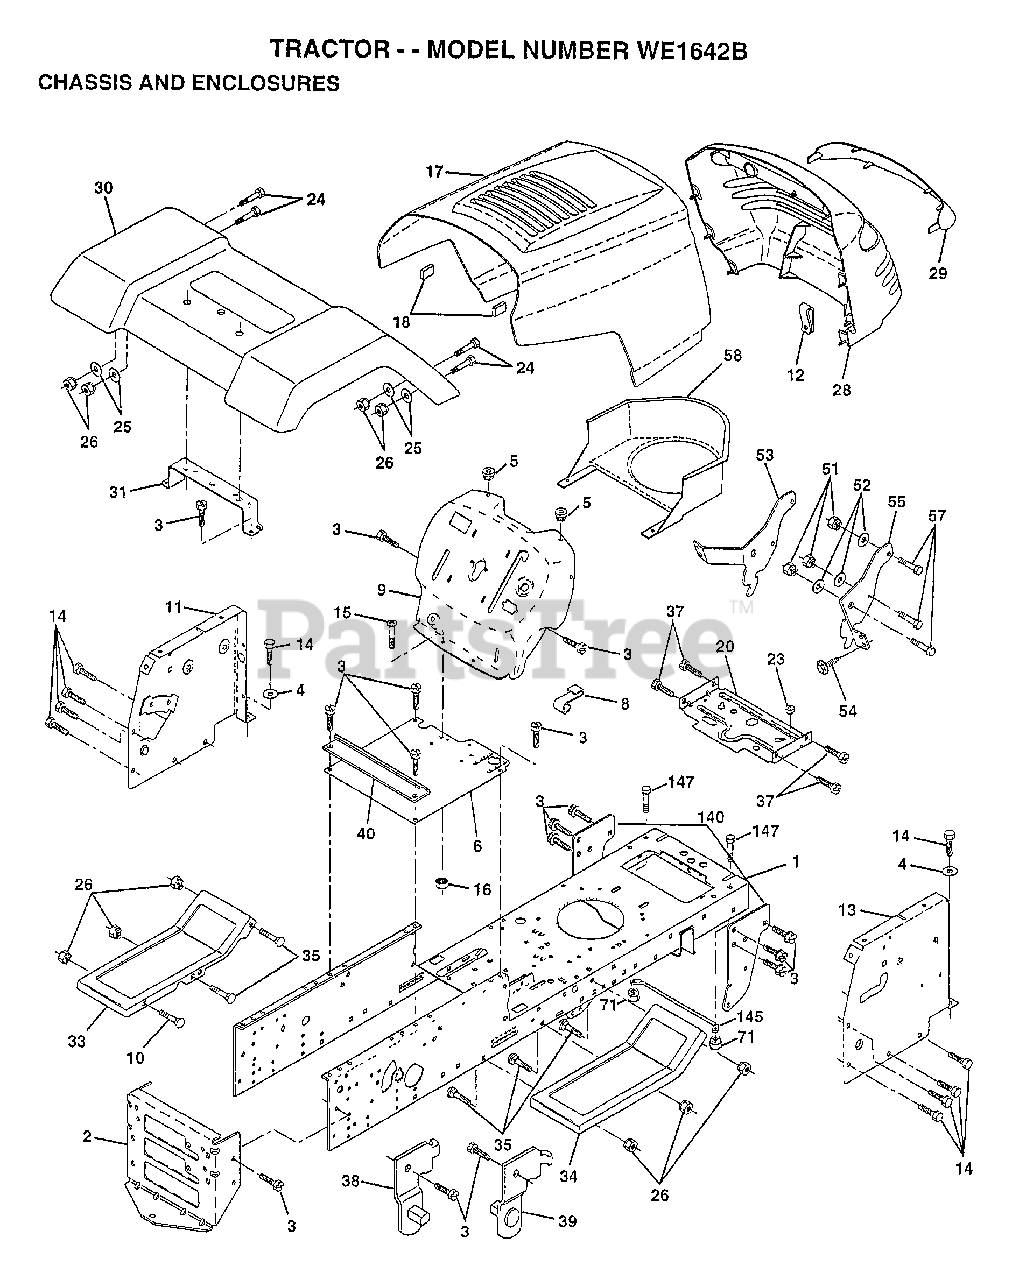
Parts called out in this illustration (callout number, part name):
1	CHASSIS ASM
3	SCREW
4	WASHER
5	BUMPER-HOOD/DASH
6	SADDLE
8	"CLIP,INSULATOR"
9	DASH.SILKSCREENED
11	"PANEL-DASH,LH"
12	CLIP.TINNERMAN
14	SCREW LT
15	SCREW
20	"PLATE-MTG,BATT/FU"
24	BOLT
25	WASHER
26	NUT
28	GRILLE-MS428
29	LENS GRILLE
30	FENDER
31	BRACKET SUPT FEND
33	FOOTREST.LH.LT/GT
34	FOOTREST.RH.LT/GT
35	BOLT
37	SCREW LT
38	BRACKET ASM LH
39	BRACKET ASM RH
40	SPACER FENDER LT
51	NUT
52	WASHER
53	BRACKET.GRILLE.LH
55	BRACKET.GRILLE.RH
58	DUCT.AIR.B&S.18HP
140	BRKT SUSPENSION
145	"ROD POVOT,CHASSIS"
147	BOLT LT
